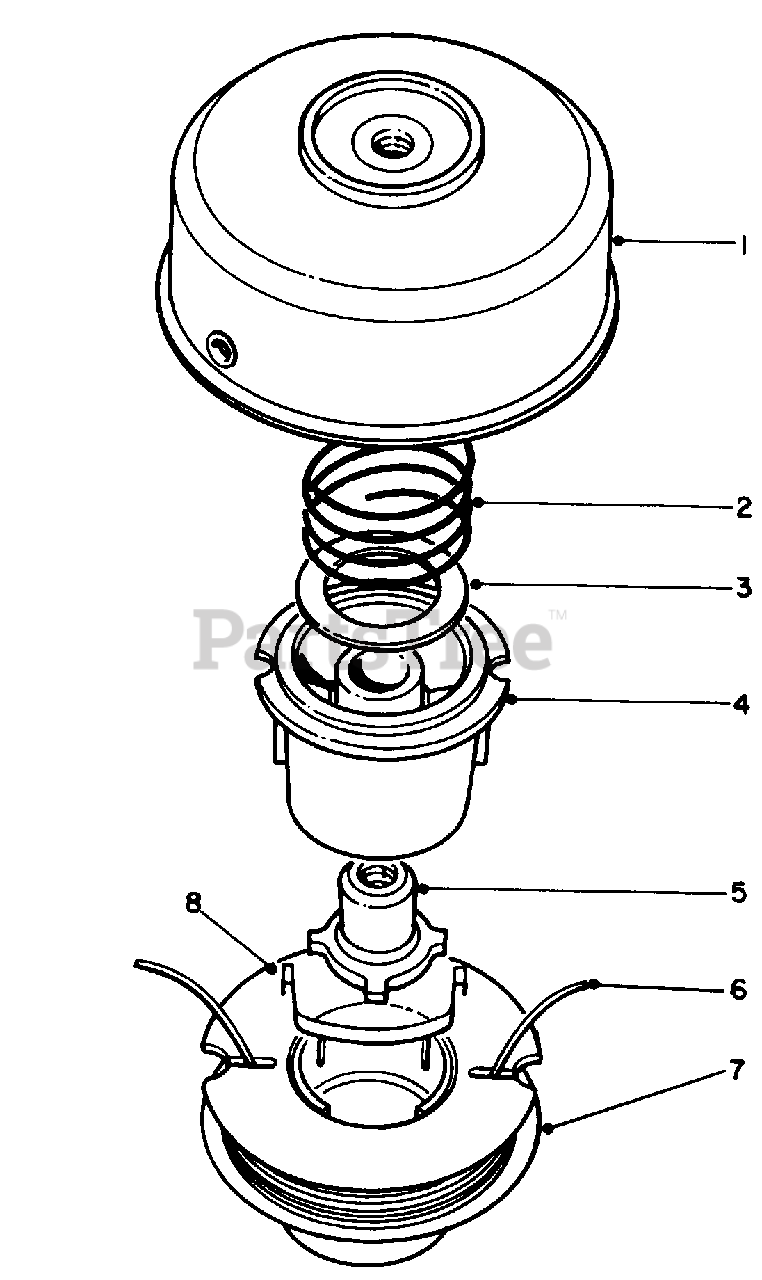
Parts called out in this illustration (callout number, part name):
1	ASM - TRIMMER DRUM & EYELET
3	WASHER-FLAT
4	SPOOL CORE
5	LH DRIVER
6	REPL LINE PKG
7	Spool Housing
8	SADDLE-SPOOL CAP
